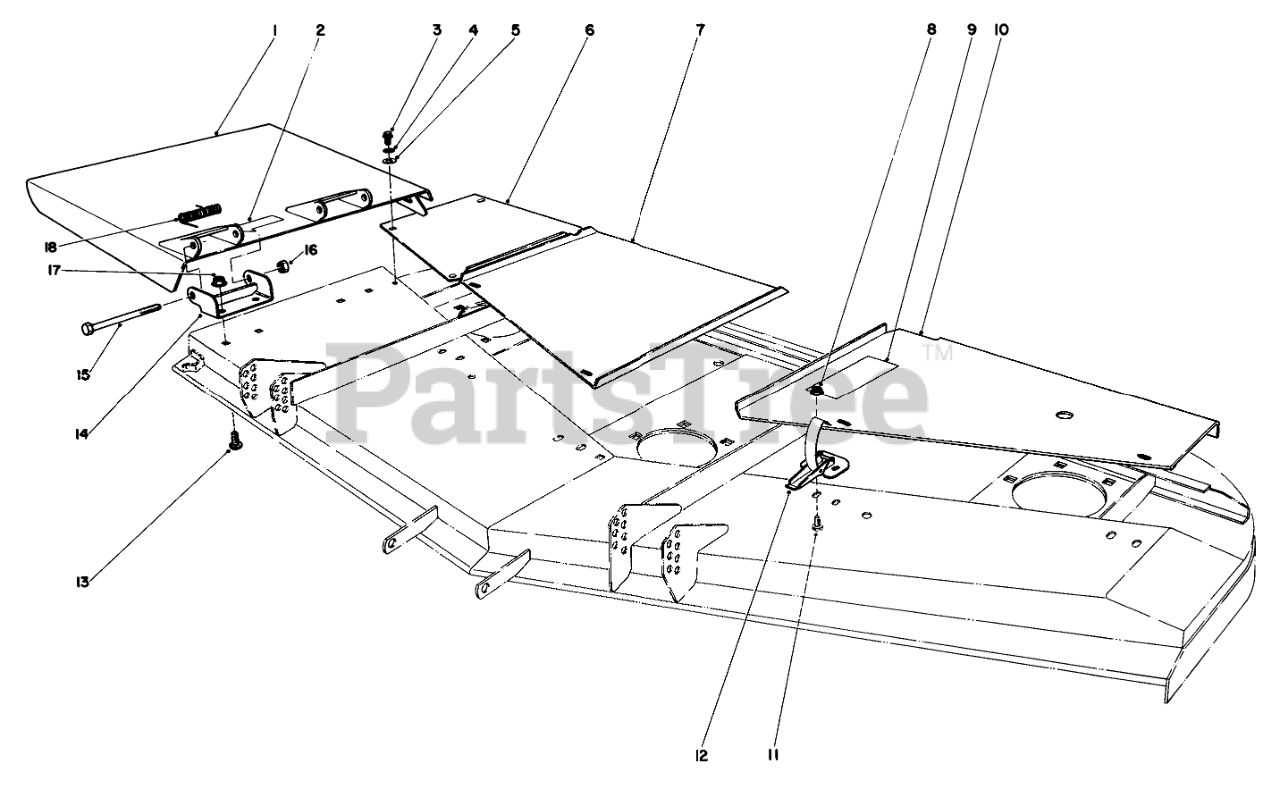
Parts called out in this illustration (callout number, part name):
1	Deflector
2	DECAL - BLADE LINE
3	SCREW THD 1/4 20 5/8
4	WASHER-LOCK
5	WASHER-FLAT
6	RH DECK COVER R
7	CTR DECK COVER R
8	NUT-LOCK, FLANGE
9	DECAL
10	Cover-Deck L.H.
11	SCREW-HWH
12	CLAMP-SLOTTED
13	SCREW-CARR
14	Bracket-Hinge
15	SCREW-HH
16	NUT-HEX
17	NUT-HHF, WHIZ
18	SPRING
